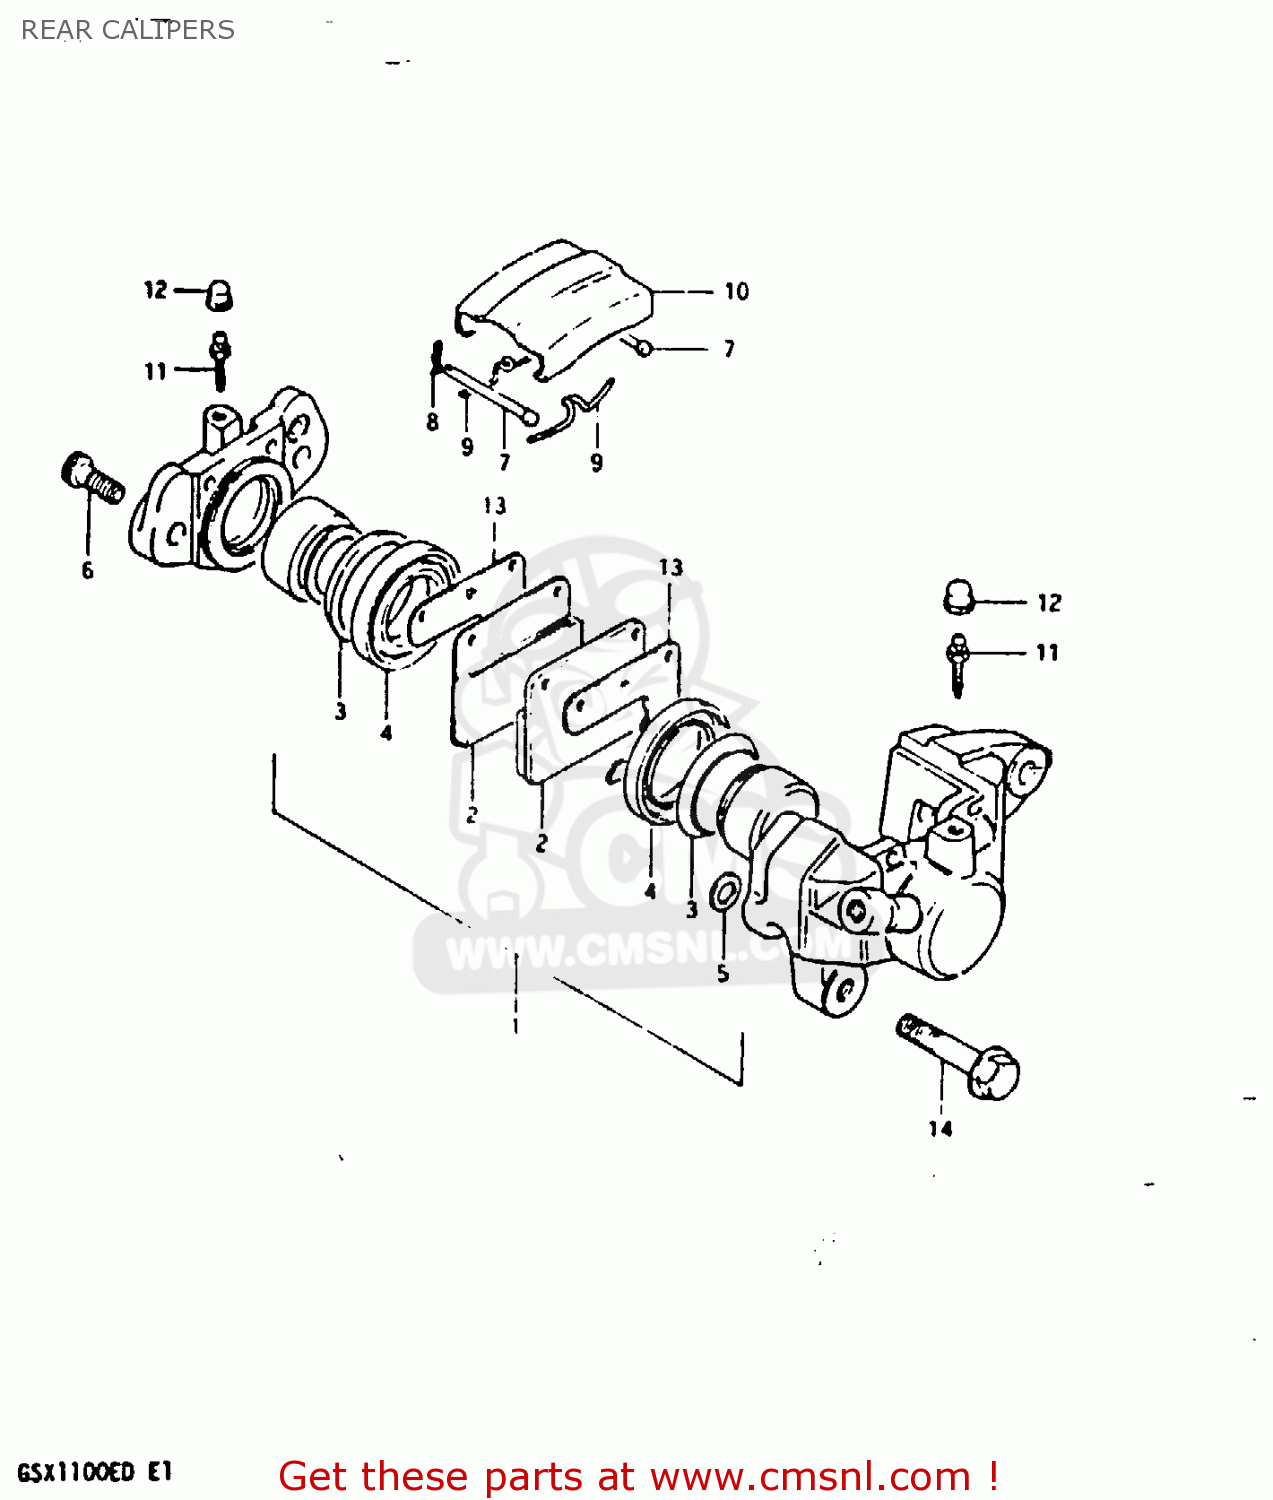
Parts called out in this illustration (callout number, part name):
1	PISTON SET
2	PAD,BRAKE
3	SEAL,PISTON
4	BOOT,PISTON
5	SEAL,PISTON
6	BOLT,HOUSING
7	PIN,PAD
8	CLIP,PAD PIN
9	SPRING
10	COVER,DUST
11	BLEEDER
12	CAP,BREATHER
13	SHIM,RR CALIPER
14	BOLT
